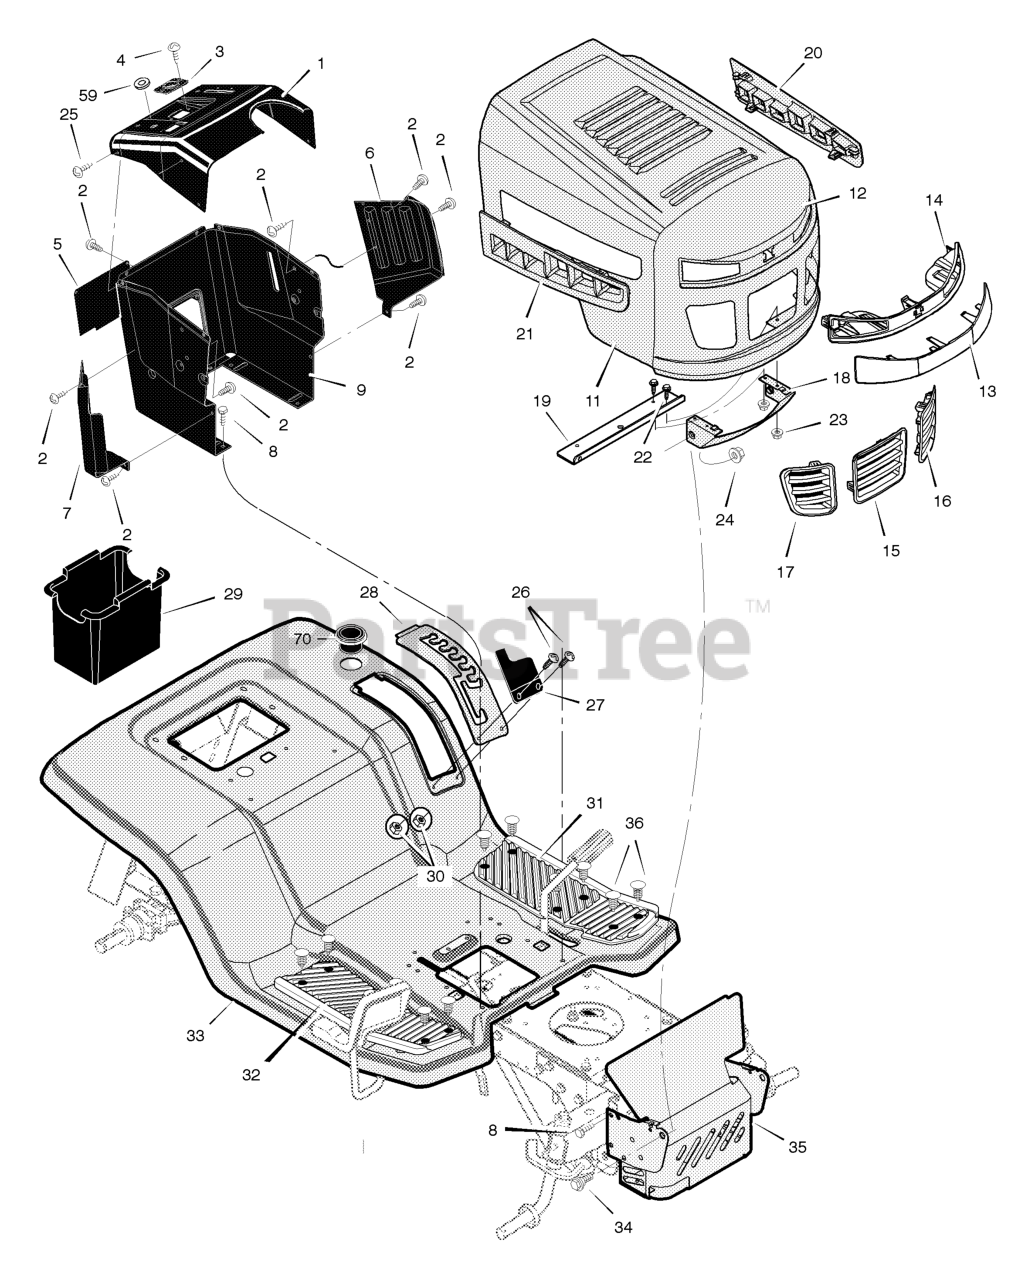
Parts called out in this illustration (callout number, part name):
2	Screw
3	Bearing, Upper Steering
5	Panel, Access
6	Panel, Left Side
7	Panel, Right Side
9	Support, Dash
11	Hood
12	Grille
14	Housing, Light
15	Insert, Center
16	Insert, Left
17	Insert, Right
18	Bracket, Lower Pivot
19	Bracket, Support
20	Insert, Left Hood
21	Insert, Right Hood
23	Nut
26	Bolt, Shoulder
28	Plate, Lift Detent
29	Container, Battery
31	Mat, Left
32	Mat, Right
33	Deck, Seat
34	Bolt
35	Shield, Heat
36	Fastener, Panel - Black
59	Grommet, Parking Brake
70	Holder, Beverage
